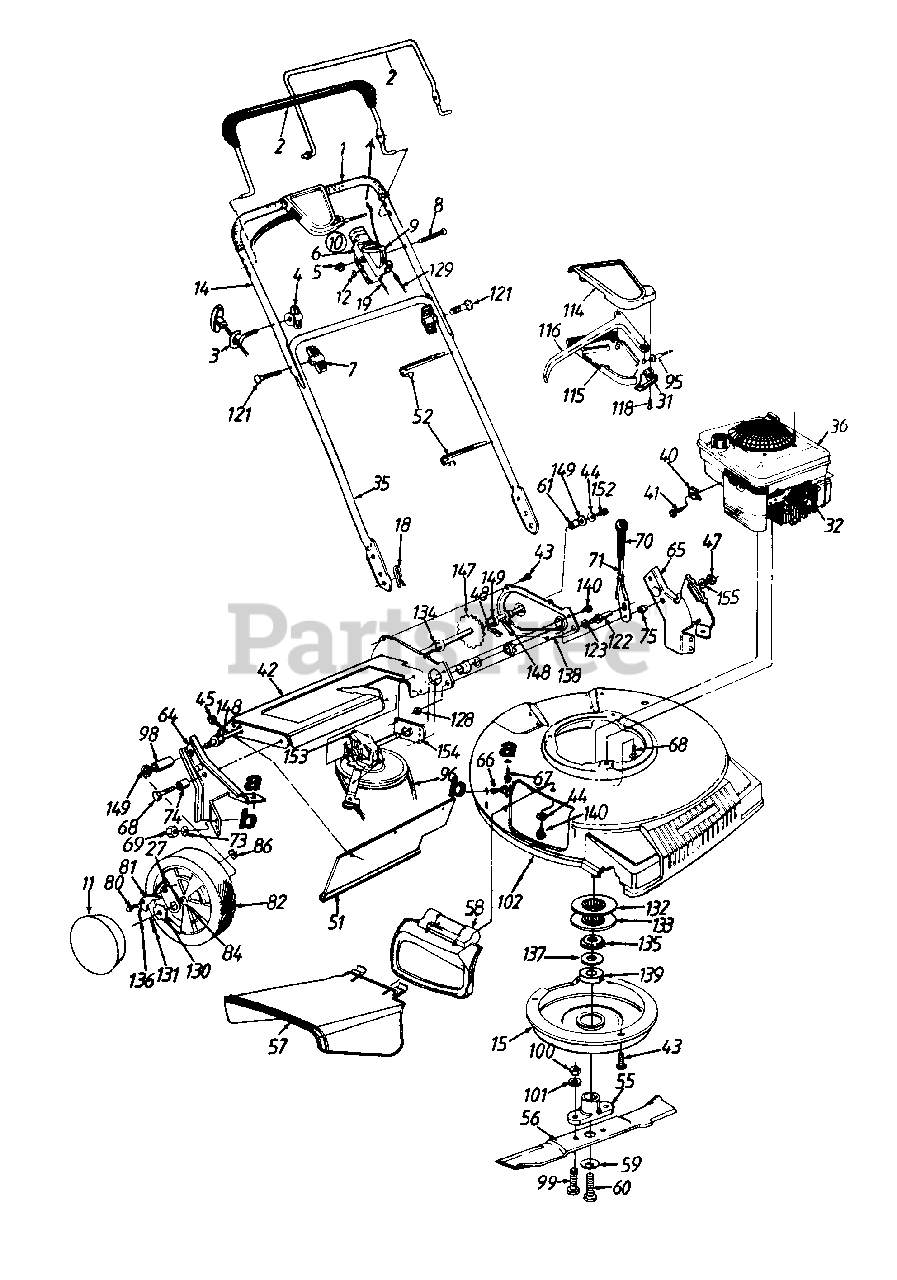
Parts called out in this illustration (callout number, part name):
1	Grip
2	Control Handle w/Plastic
3	Rope Guide
4	Handle Knob 1/4-20 Thd.
5	Hex L-Nut 1/4-20 Thd.
6	Throttle Body
7	Hand Knob
8	Oval C-Sunk Scr.
9	Throttle Lever
10	Throttle Box Comp.
11	Hub Cap
12	Spr. Wash. .66" I.D.
19	Throttle Control Wire 55" Lg.
27	Pawl Plate
31	S.P. Control Cover
32	Spark Plug Insulator
36	Engine
40	Cable Clamp
41	Hex Self-Tap Scr. #10-32 x .62"
44	Bell-Wash. 1/4" I.D.
45	Hex AB-Tap Scr. 1/4 x .62"
47	Hex Patch L-Nut 3/8-24 Thd.
48	#48 Chain .500" Pitch x 38 Links
51	Rear Flap 4.8" x 17.5" Lg.
52	Cable Tie
55	Blade Adapter
56	21" Mulching Blade
57	Chute Ass'y.
58	Mulching Plug Ass'y.
59	Bell-Wash. .39" I.D.
60	Hex Bolt 3/8-24 x 2.5"
61	Spacer .513" I.D.
67	Hex B-Tap Scr. 5/16-18
68	Hex TT-Tap Scr. 3/8-16
69	Hex Nut 5/16-18 Thd.
71	Height Adj. Lever
73	Bell-Wash. 5/16" I.D.
74	Spacer .383" I.D.
75	Shld. Spacer .5" Dia.
80	Shld. Scr. .342" Dia. x .268
81	Pawl - R.H
82	Wheel Ass'y. Comp.- Rear
84	Sleeve Bearing 1/2" I.D.
86	Weld Top L-Nut 1/4-20 Thd.
95	S.P. Cable - 44" Lg.
96	"V"-Belt
98	Sleeve .526" I. D
99	Hex Bolt 3/8-24 x 1.0" Lg.
100	Hex Nut 3/8-24 Thd.
101	L-Wash. 3/8" I.D.
115	Self-Propelled Control Cover
116	Control Lever
118	Fl-"C"-Sunk Hd. Tap Scr. #10 x .75" Lg.
121	Curved Hd. Bolt 5/16-18 x 2" Lg.
122	Shld. Pin 1.43" Lg.
123	L-Wash. 3/8" I.D.
128	Hex Jam Nut 3/8-24 Thd.
129	Control Cable - 39"
130	Ratchet Wheel 1.62" O.D.
131	Cotter Pin 1/8" Dia. x 1"
132	Pulley Half
133	Pulley Half
134	Hex Flange Bearing
135	Spr. Wash. .89" I.D.
136	Spring - Nylon
137	Fl-Wash. .85" I.D.
140	Hex S-Tap Scr. 1/4-20 x .50"
147	Rear Shaft Ass'y. 21.44" Lg.
148	Hex Flange Brg. .506" I.D.
149	Fl-Wash. .531" I.D. x .930"
152	Hex Bolt 1/4-20 x .62" Lg.(Grade 5)
153	Transmission Comp.
155	Fl-Wash. .385" I.D. x .87" O.D.
